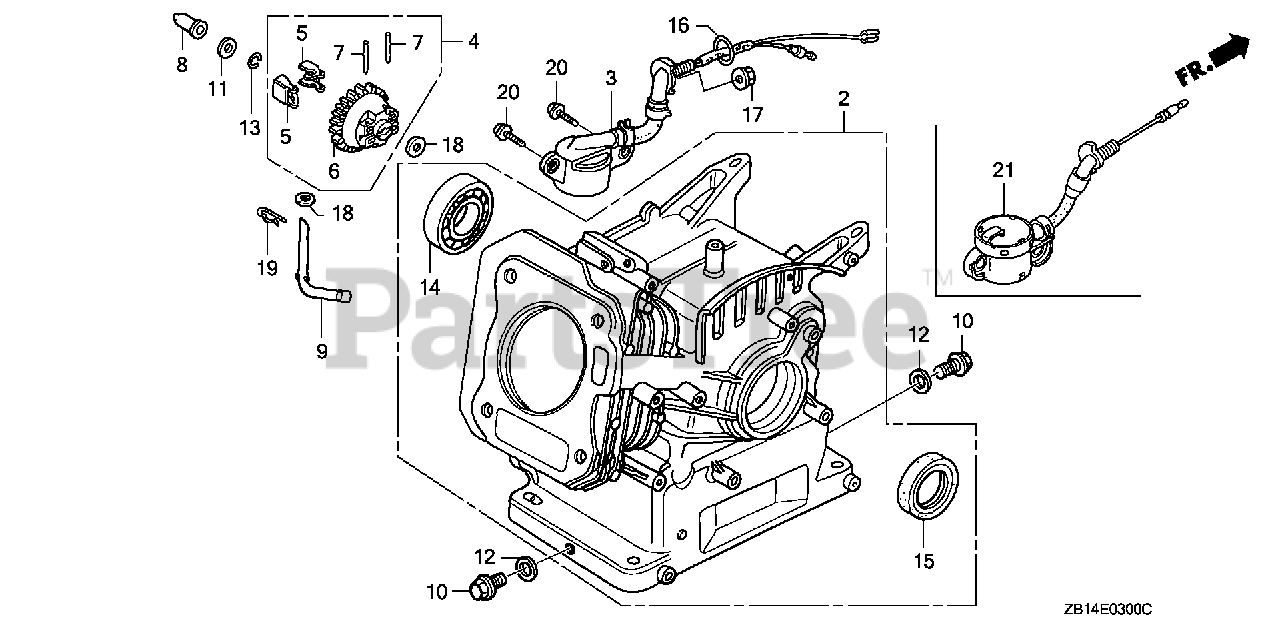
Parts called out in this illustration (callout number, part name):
2	CYLINDER ASSY. (OIL ALERT)
3	SWITCH ASSY., OIL LEVEL
4	GOVERNOR ASSY.
5	WEIGHT, GOVERNOR
6	HOLDER, GOVERNOR WEIGHT
7	PIN, GOVERNOR WEIGHT
8	SLIDER, GOVERNOR
9	SHAFT, GOVERNOR ARM
10	BOLT, DRAIN PLUG
11	WASHER, THRUST (6MM)
12	WASHER, DRAIN PLUG (10.2MM)
13	CLIP, GOVERNOR HOLDER
14	BEARING, RADIAL BALL (6205TMB) (NTN)
14	BEARING, RADIAL BALL (6205)
15	OIL SEAL (25X41X6)
16	O-RING (14MM) (ARAI)
17	NUT, FLANGE (10MM)
18	WASHER, PLAIN (6MM)
19	PIN, LOCK (8MM)
20	BOLT, FLANGE (6X12)
